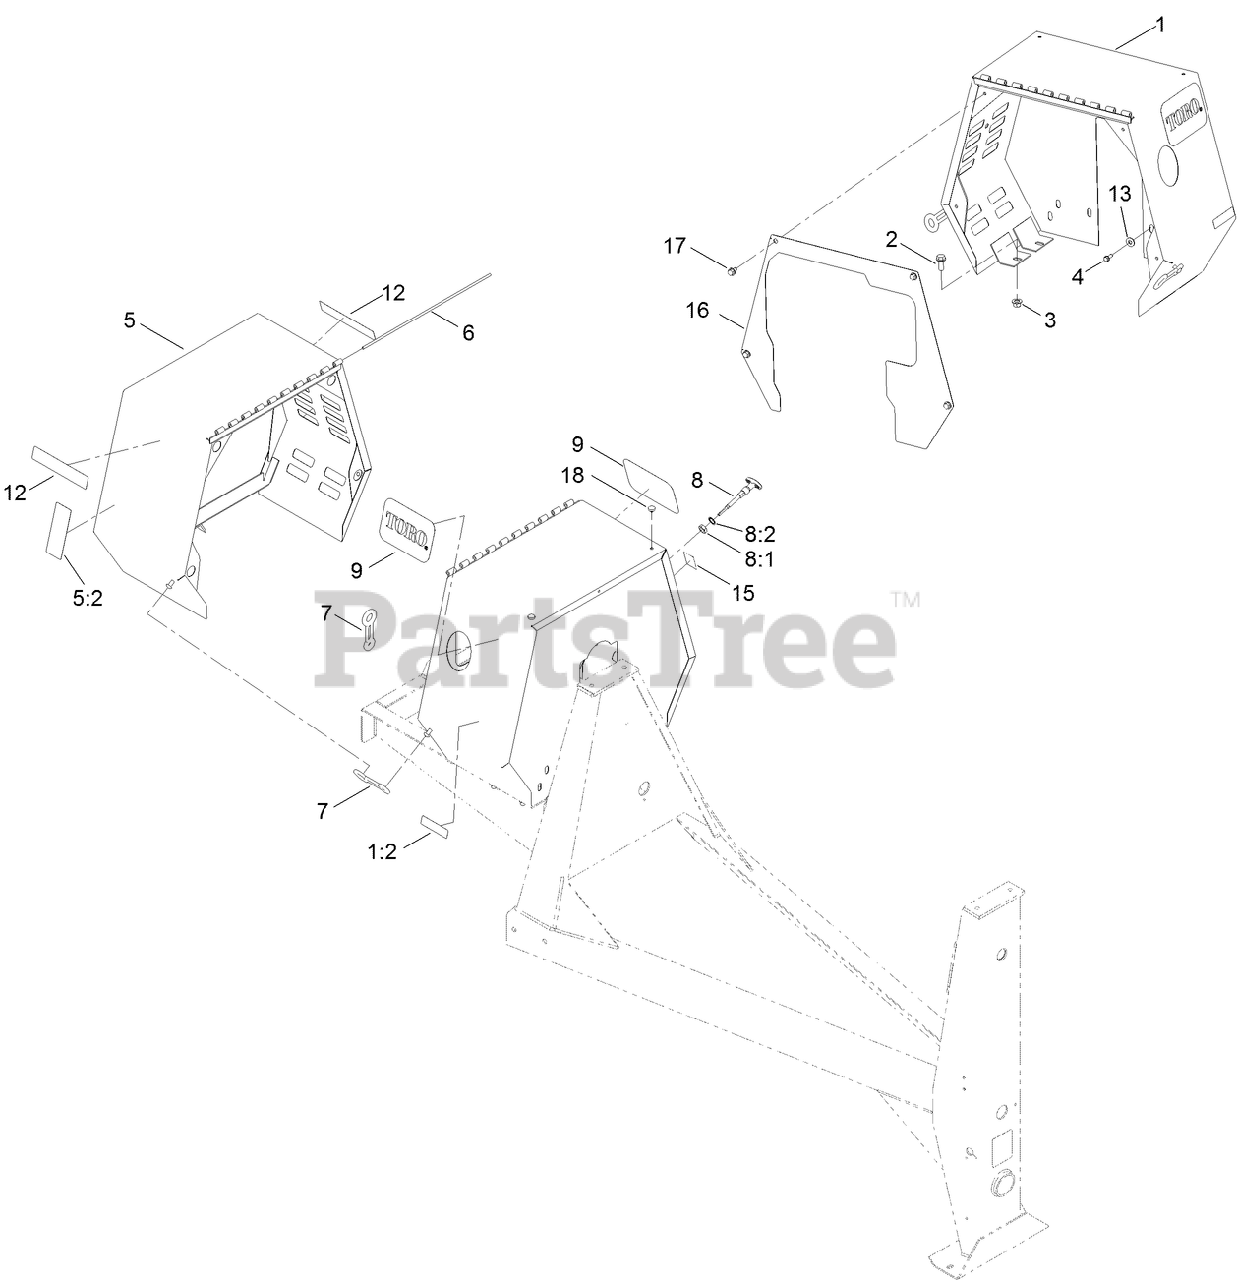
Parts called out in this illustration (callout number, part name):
1	COWL ASM
1:2	DECAL-ARRESTER, SPARK
2	SCREW-HHF
3	NUT-LOCK
4	SCREW-THD ROLL, HWH
5	MOVABLE COWL ASM
5:2	DECAL-WARNING
7	LATCH-RUBBER
8	CABLE-THROTTLE, 125CM
8:1	NUT-JAM
8:2	WASHER-LOCK
9	DECAL
13	WASHER-FLAT
15	DECAL-THROTTLE, DIESEL
16	PLATE-DRIVE, GUARD
17	SCREW-HWH
18	BUMPER
